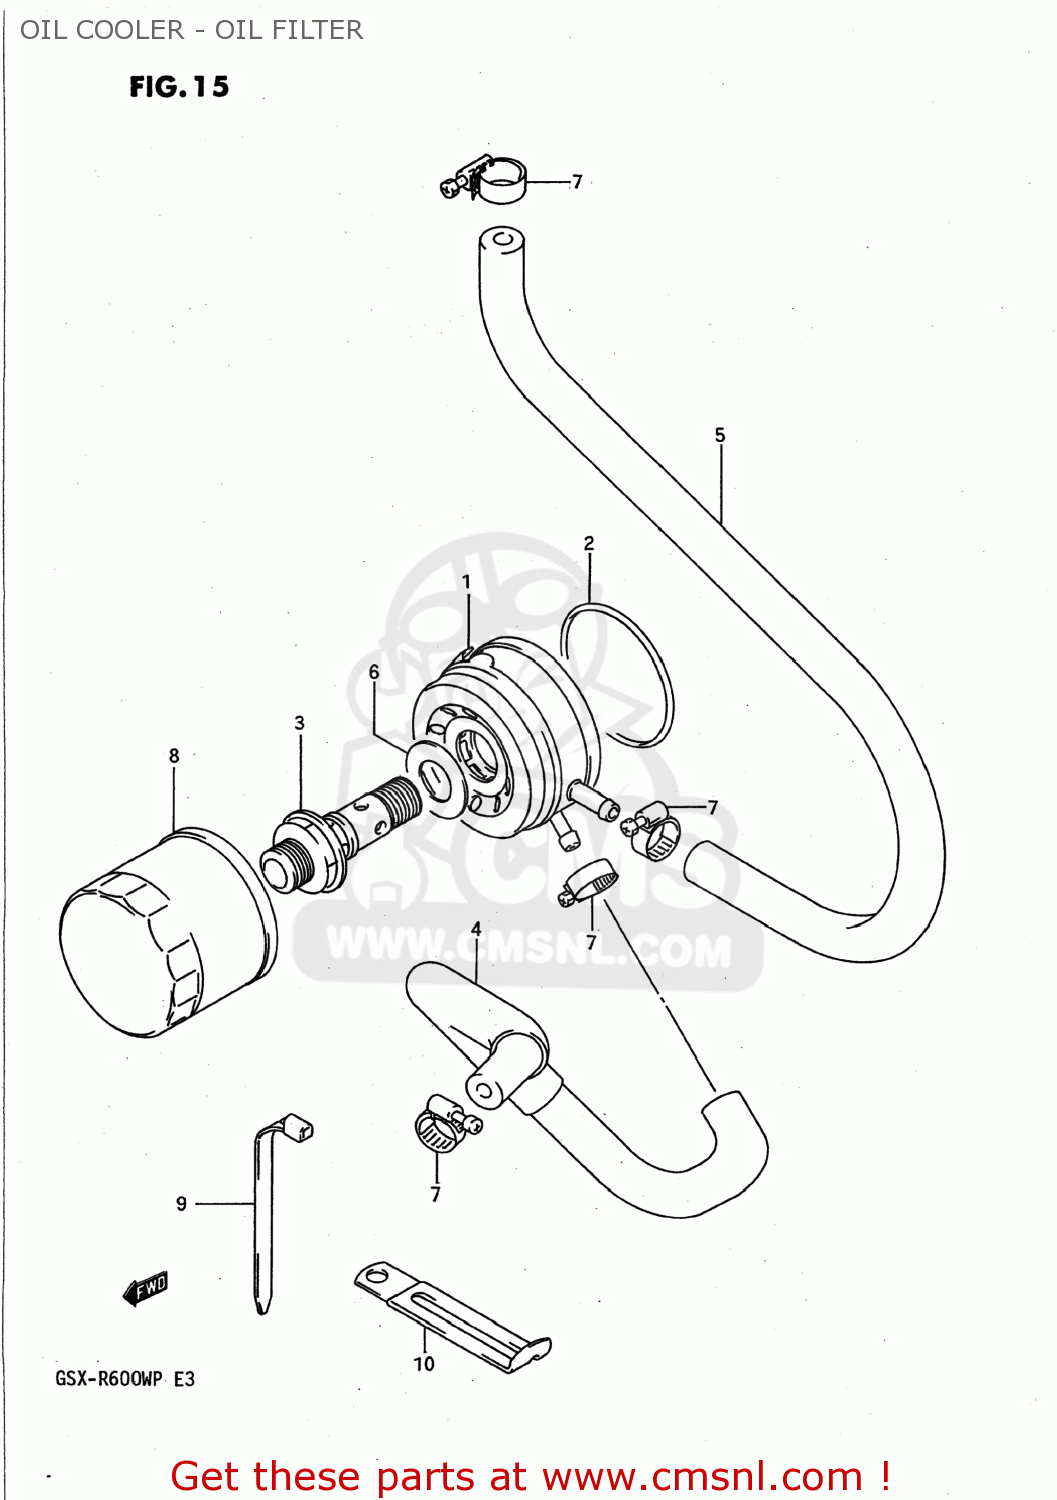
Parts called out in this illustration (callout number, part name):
1	COOLER ASSY,OIL
2	O RING(D:3.1,ID:63.9)
3	BOLT,OIL COOLER UNION
4	HOSE,OIL COOLER WATER IN
5	HOSE,OIL
6	SHIM,PRIMARY SHAFT (T=0)
7	CLAMP
8	FILTER ASSEMBLY,ENGINE OIL
9	CLAMP(L:165)
10	CLAMP
